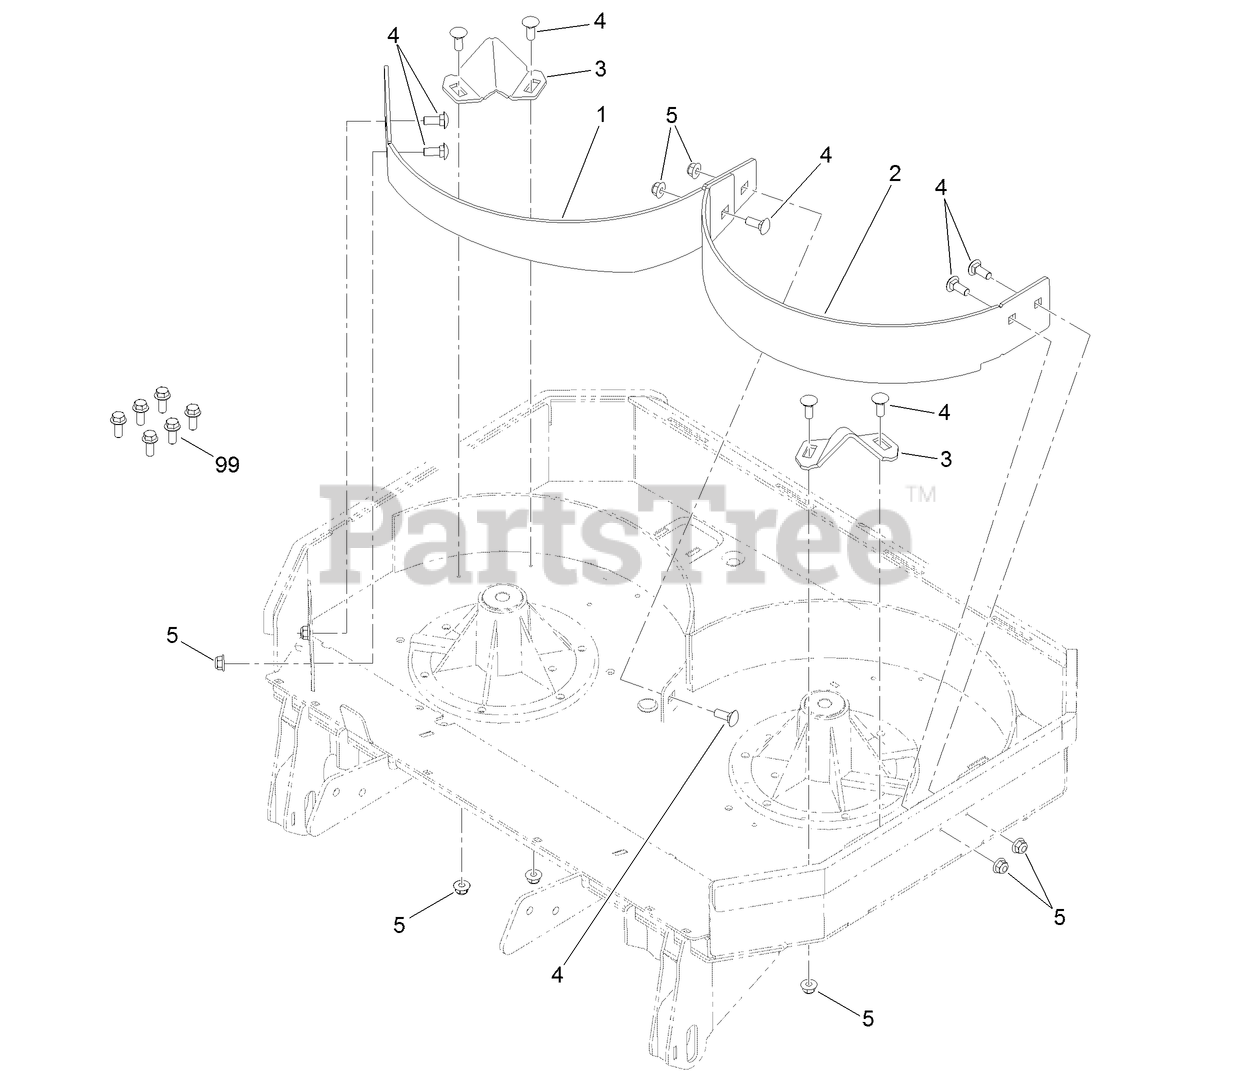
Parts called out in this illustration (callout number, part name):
1	BAFFLE-RH
2	BAFFLE-LH
4	BOLT-CARR
5	NUT-HF, NI
99	SCREW-HHF
